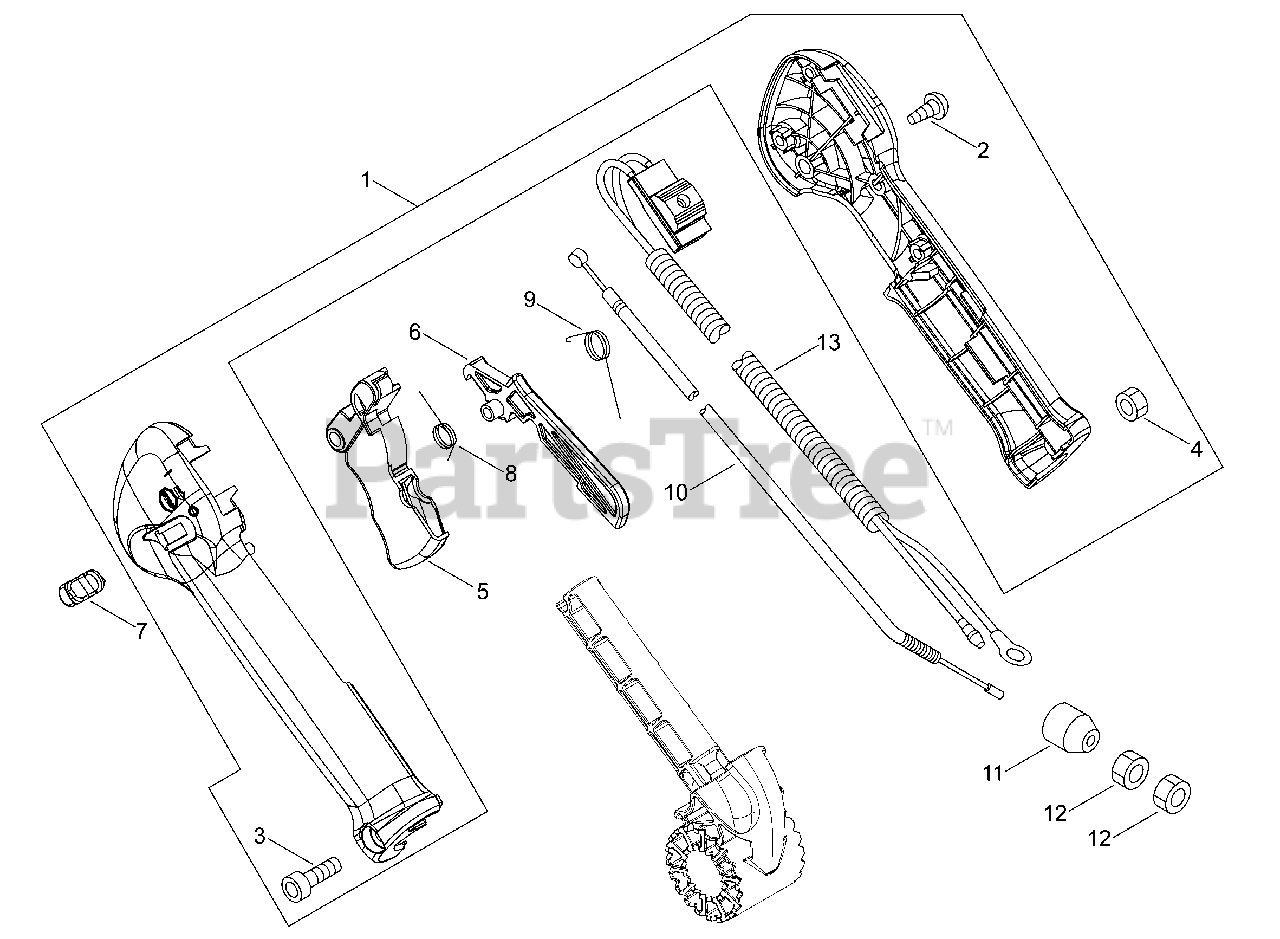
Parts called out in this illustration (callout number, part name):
1	THROTTLE CONTROL ASSY
2	SCREW 4×16
4	NUT M5
5	TRIGGER, THROTTLE
6	LOCKOUT, THROTTLE
8	SPRING, TORSION
9	SPRING, TORSION
10	CABLE, THROTTLE
11	CAP, DUST
13	SWITCH, ON-OFF
